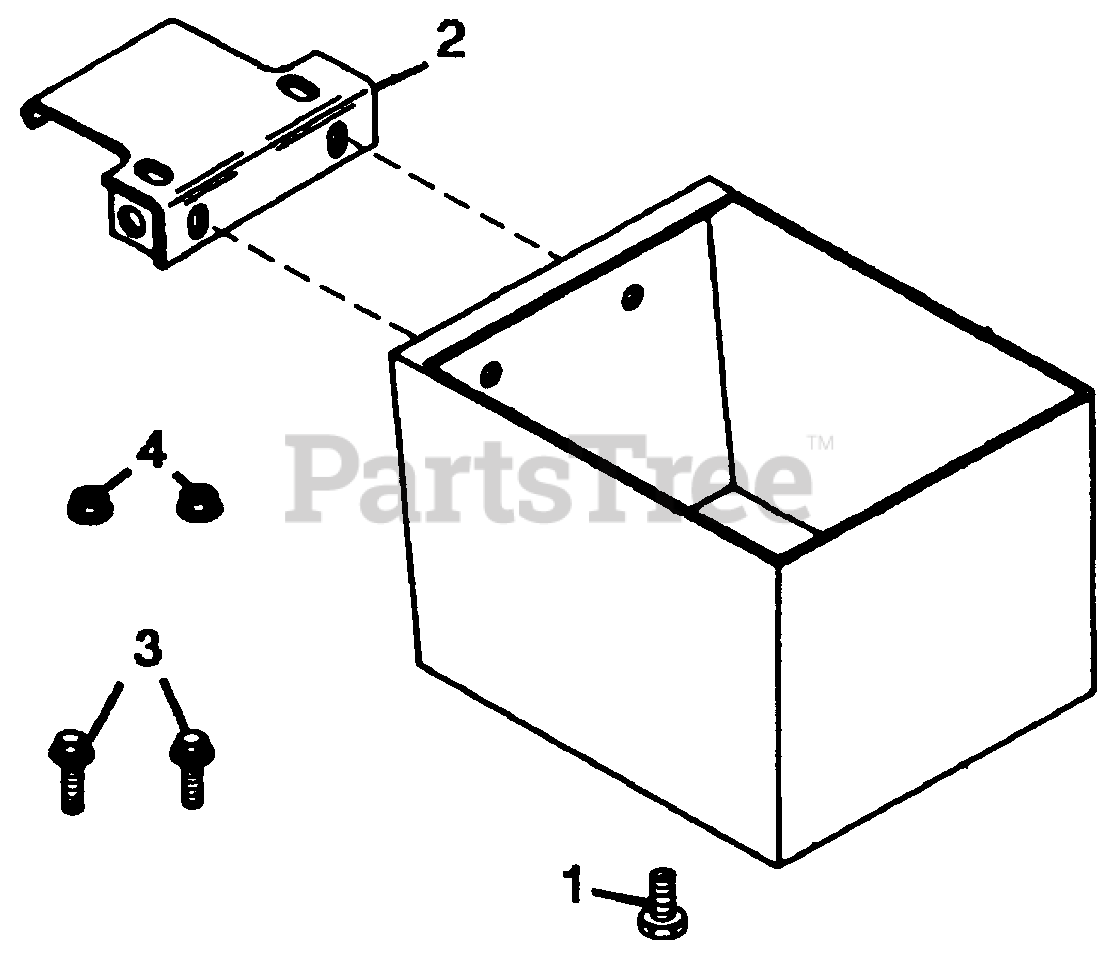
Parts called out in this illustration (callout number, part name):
1	Bolt, Hex 1/2-13x.75
2	Hook, Mount
3	Screw, Flange 5/16-18x.625
4	Nut, Lock 5/16-18
